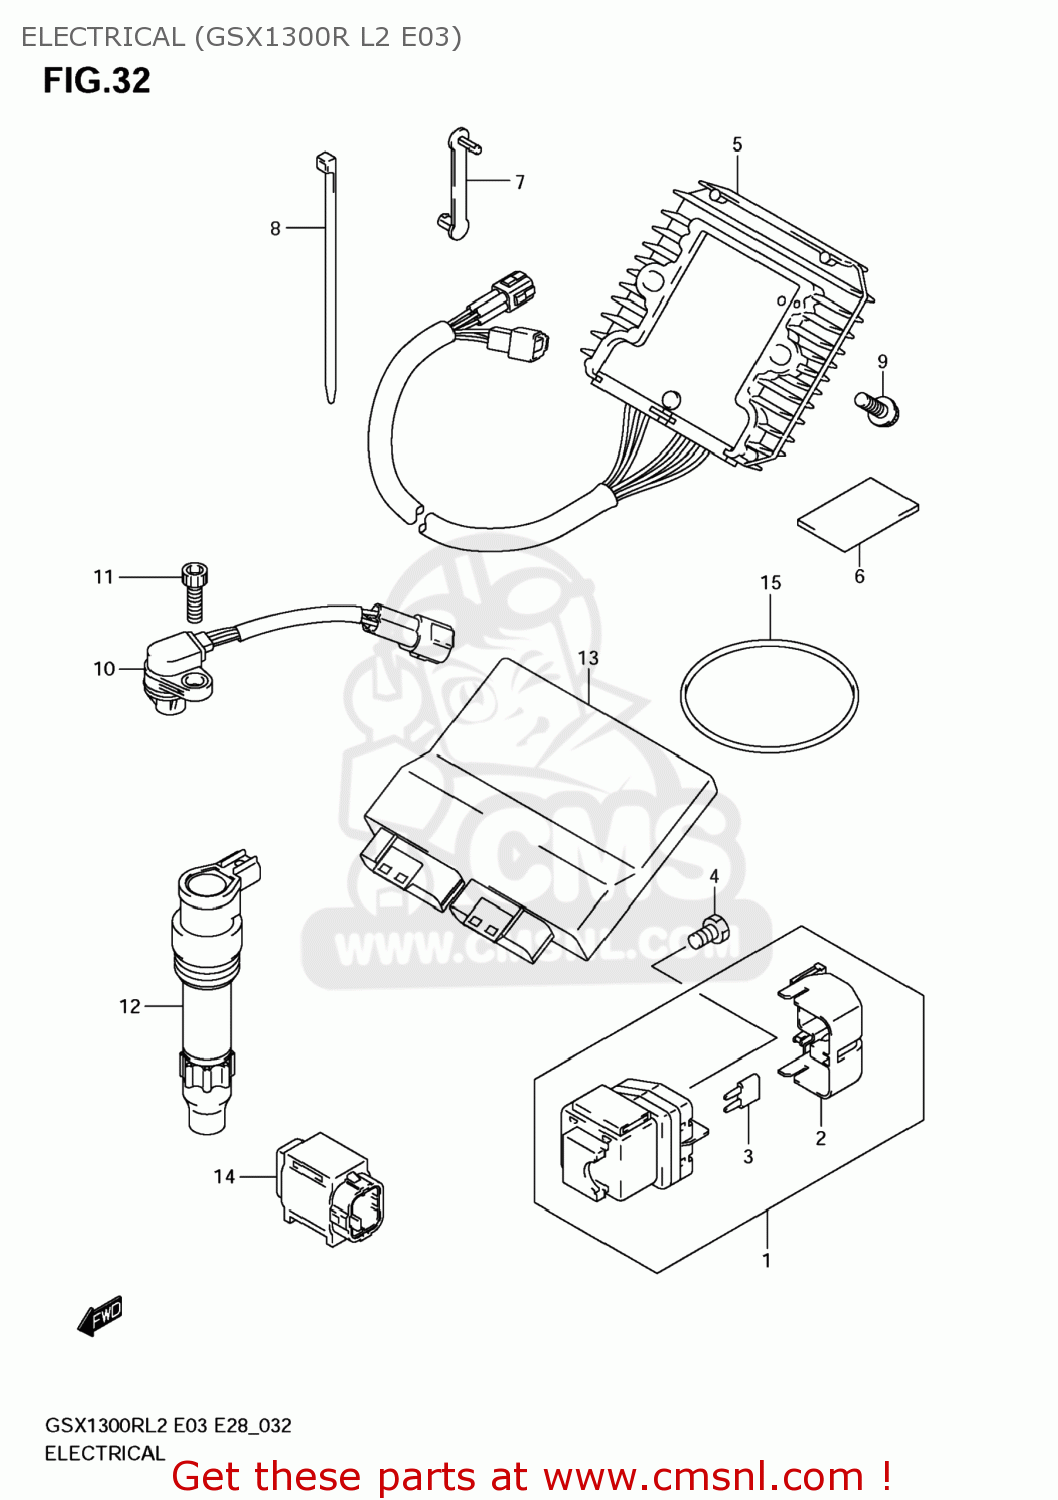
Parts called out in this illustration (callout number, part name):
1	RELAY ASSY,STARTING MOTOR
2	COVER
3	FUSE(30A)
4	SCREW(6X8)
5	RECTIFIER ASSY
6	CUSHION(30X50X3)
7	CLAMP(L:63)
8	CLAMP(L:145)
9	SCREW
10	SENSOR ASSY,CAM POSITION
11	BOLT
12	COIL ASSY,IGNITION
13	CONTROL UNIT,FI
14	SENSOR ASSY,FUEL CUT
15	O RING(D:3.5,ID:76)
